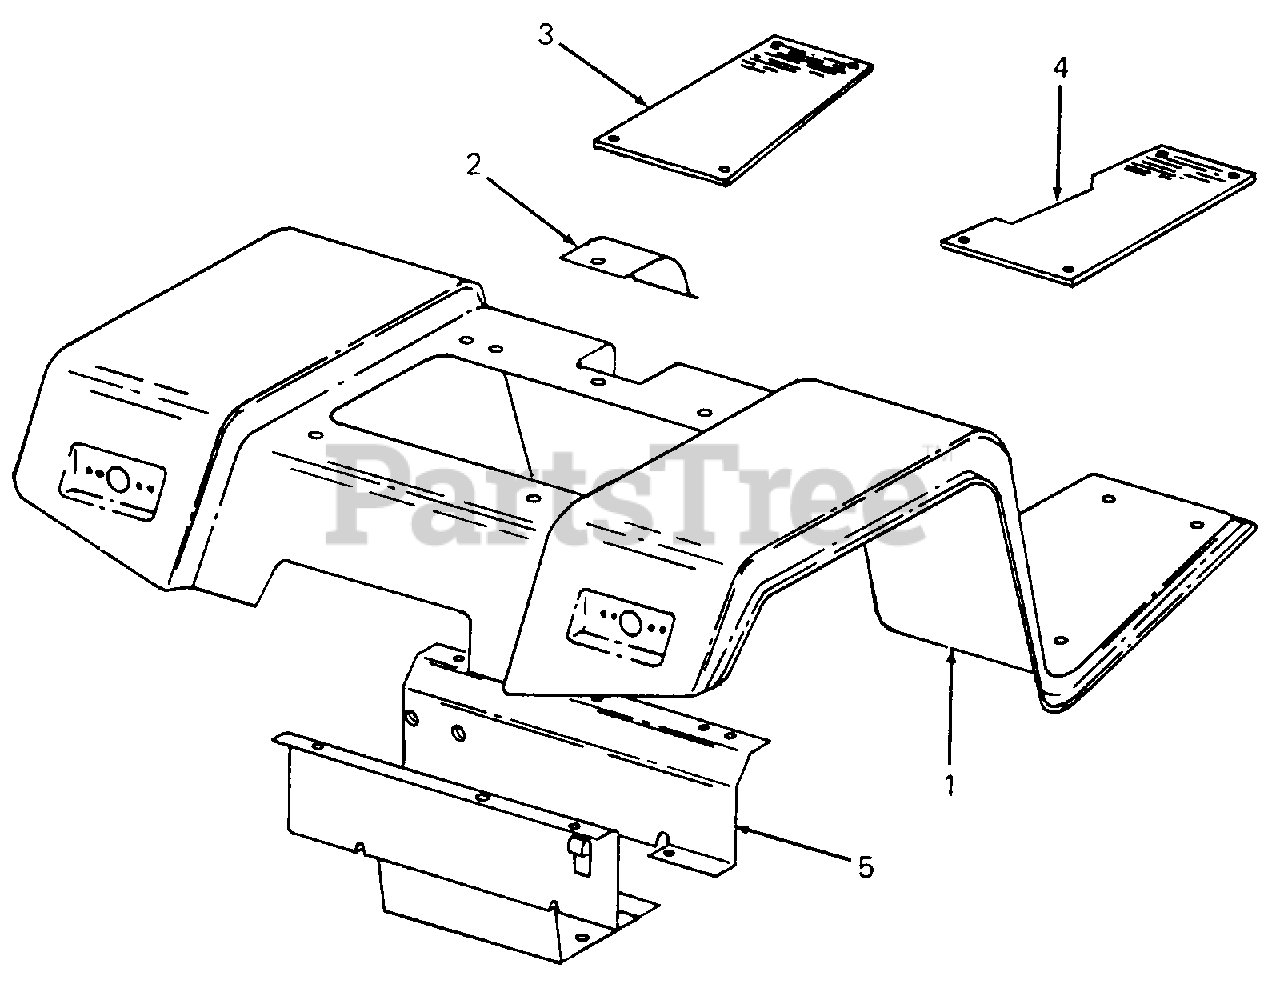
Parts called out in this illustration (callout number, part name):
3	Pad, LH Foot
4	Pad, RH Foot
5	Support, Fender
